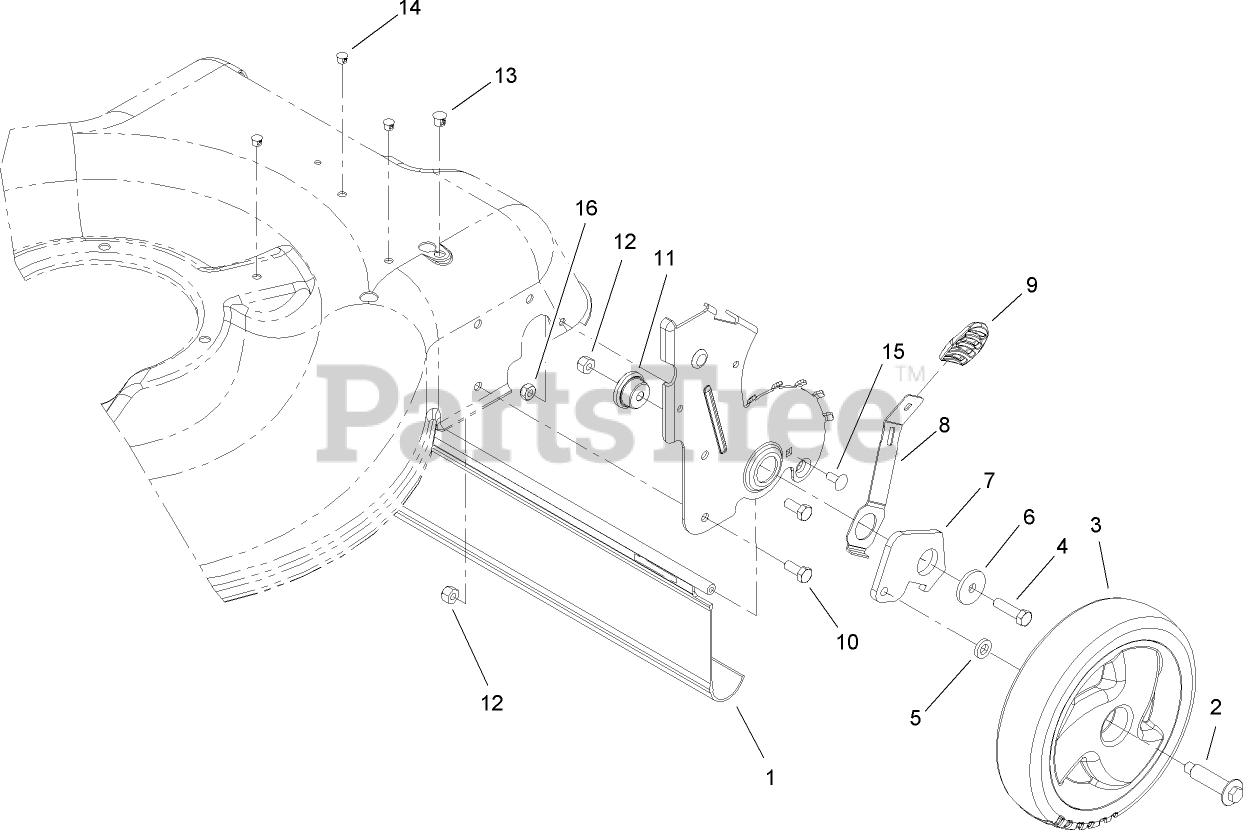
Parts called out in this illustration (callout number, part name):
1	SHIELD-TRAILING
2	BOLT-SHOULDER
3	WHEEL ASM (59505)
4	SCREW-HH
5	WASHER-BOLT, WHEEL
6	WASHER-FLAT
7	ARM-PIVOT, REAR (LH)
8	ARM-SPRING
9	KNOB-LEVER, HOC
10	SCREW-HH
11	BUSHING-MOUNT, HOC
12	NUT-LOCK, NI
13	PLUG-DOME
14	PLUG-DOME
15	SCREW-CARR
16	NUT-LOCK, NI
